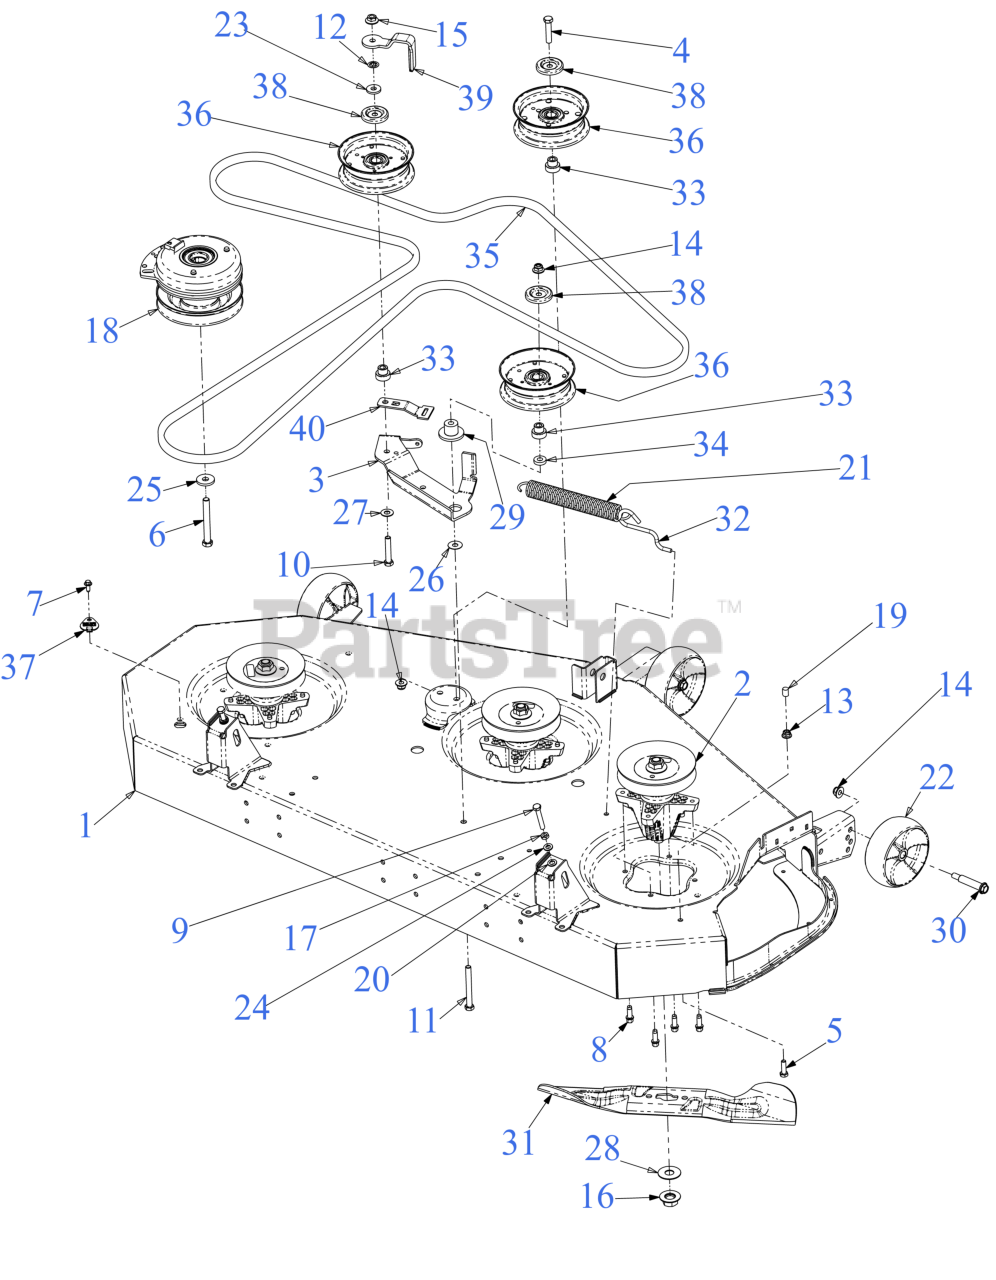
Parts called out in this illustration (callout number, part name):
1	54" FAB DECK SHELL
2	SPINDLE ASSEMBLY
3	DECK IDLER BRACKET
4	HEX SCREW 3/8-16 x 1.75 GR5
5	SCREW 5/16-18 x 1.0 GR5
6	SCREW 7/16-20 x 3.5 GR5
7	SCREW M6-1 x .625
8	SCREW 5/16-18 x .875
9	SCREW-FULL THREAD 5/16-18 GR5
10	SCREW 3/8-16 x 2.0 GR 8
11	SCREW 3/8-16 x 3.25 GR8
13	FLANGE LOCK NUT 5/16-18
14	NUT
15	FLANGE LOCK NUT
16	HEX FLANGE NUT 5/8-18 GR5
17	HEX NUT
18	ELECTRIC PTO CLUTCH
20	NUT RIVET 5/16-18
21	EXTENSION SPRING
22	DECK WHEEL (5.0 DIA x 1.875)
22	Cub Cadet 5" DECK WHEEL SET (06305A) (W/BOLT)
23	FLAT WASHER .385 x 1.00 x .135
24	FLAT WASHER
25	FLAT WASHER .445 x 1.248 x .170
26	FLAT WASHER
27	FLAT WASHER .401X.88
28	FLAT WASHER .635X1.585X.062 HDN
29	SHOULDER SPACER
30	SHOULDER BOLT (.50 X 2.0 x 3/8 -16)
31	18.611" BLADE (2IN1) (S SHAPE CENTER HOLE)
31	Cub Cadet 54" HI LIFT BLADE SET (S SHAPE CENTER HOLE) (-05086)
31	Troy-Bilt 54" HI LIFT BLADE SET (S SHAPE CENTER HOLE)
31	18.611" XTREME BLADE (2IN1) (S SHAPE CENTER HOLE)
31	Cub Cadet 54" XTREME BLADE SET (S SHAPE CENTER HOLE) (-05086-X)
31	Troy-Bilt 54" XTREME BLADE SET (S SHAPE CENTER HOLE)
31	18.611" LOW LIFT (S SHAPE CENTER HOLE)
31	Cub Cadet 54" LOW LIFT BLADE SET (S SHAPE CENTER HOLE) (-05086-L)
31	Troy-Bilt 54" LOW LIFT BLADE SET (S SHAPE CENTER HOLE)
32	DECK SPRING HOOK
33	SHOULDER SPACER
35	V-BELT B SEC x 148.25
35	Cub Cadet 54" DECK DRIVE BELT
36	IDLER PULLEY 4.50" DIA
37	DECK WASH PLUG
38	IDLER PULLEY CAP
39	BELT KEEPER
